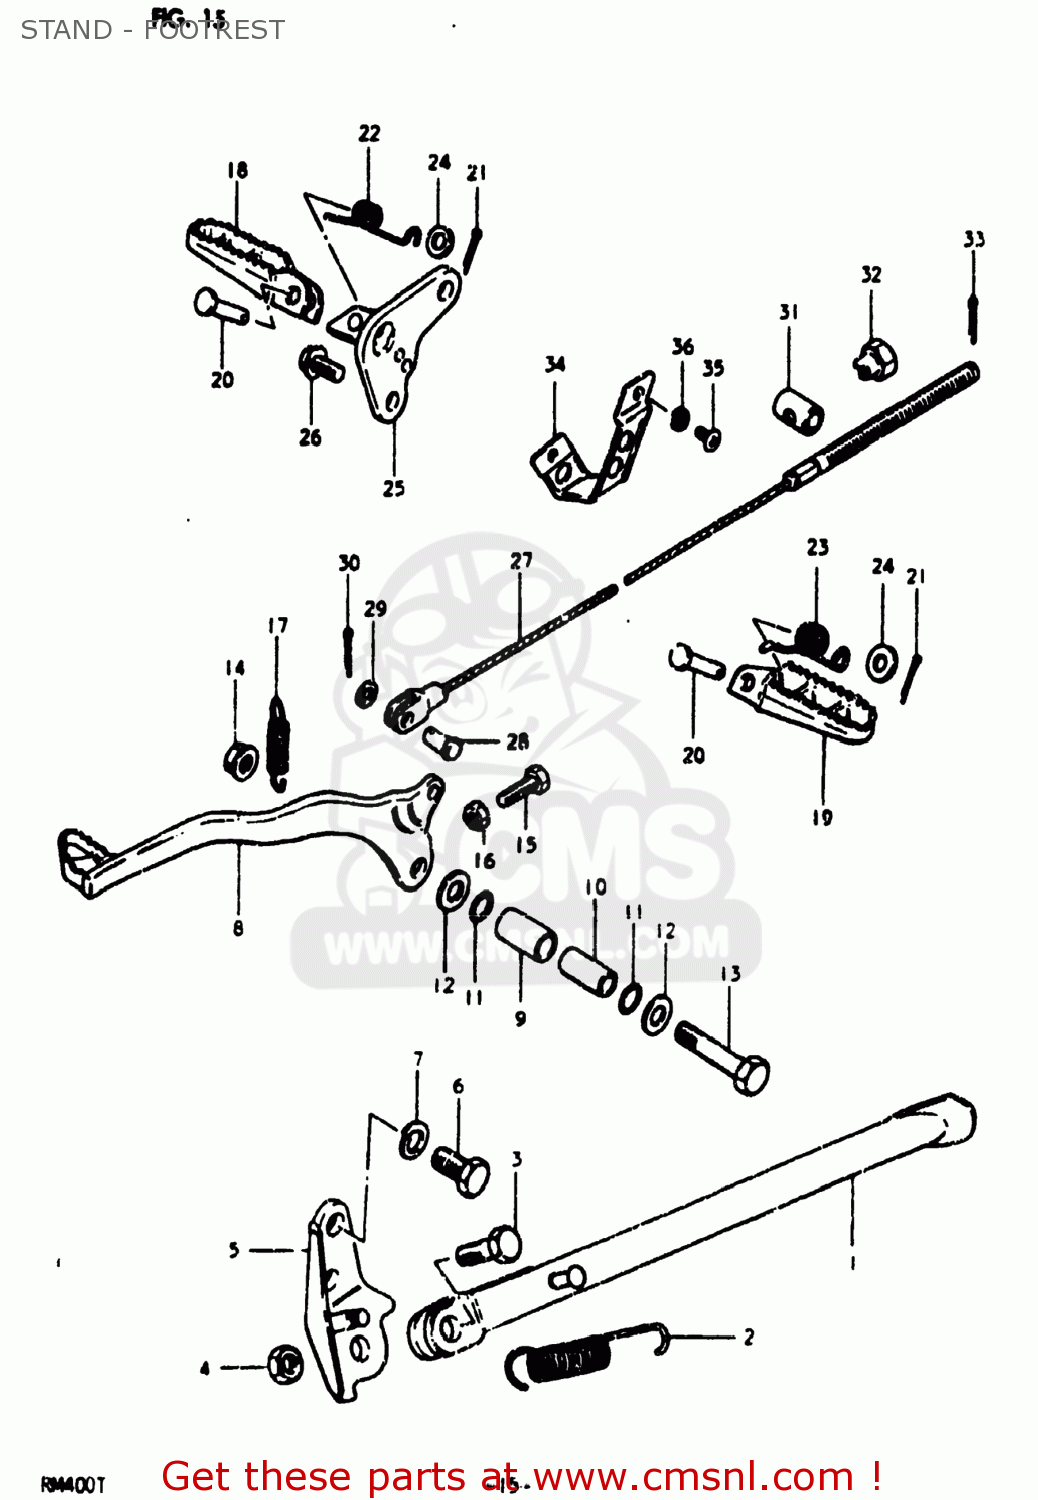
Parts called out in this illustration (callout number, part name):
1	STAND,SIDE
2	SPRING
3	BOLT(10X30)
4	NUT
5	BRACKET,PROP STAND
6	BOLT(10X19)
7	LOCK WASHER
8	PEDAL,BRAKE
9	BUSH
10	SPACER(10X14X32.2)
11	O RING(D:1.5,ID:13.8)
12	WASHER
13	BOLT
14	NUT
15	BOLT(6X23)
16	NUT
17	SPRING
18	RUBBER,FRONT FOOTREST
19	FOOTREST
20	PIN
21	PIN 30X20
22	SPRING
23	SPRING
24	WASHER
25	HOLDER,FRONT FOOTREST,RIGHT
26	BOLT(10X20)
27	CABLE,RR BRAKE
28	PIN(L:17.5)
29	WASHER
30	PIN 20X20
31	PIN
32	NUT
33	PIN
34	GUIDE,CABLE
35	SCREW
36	LOCK WASHER
